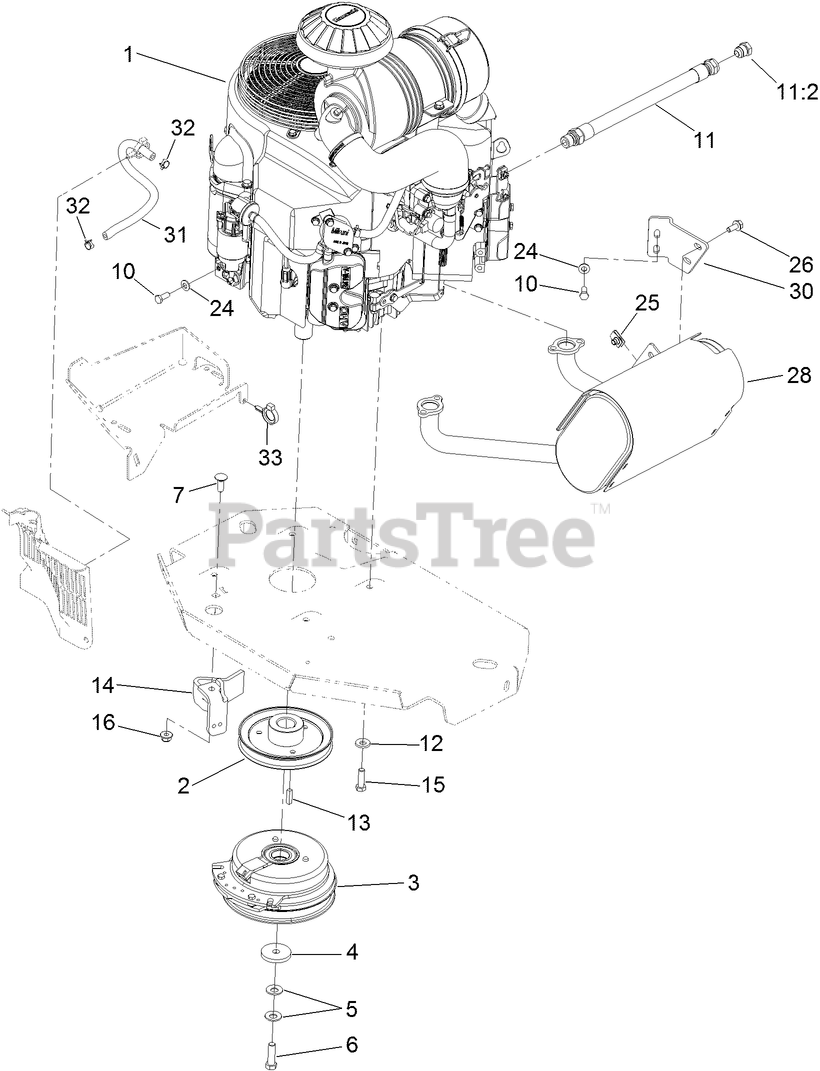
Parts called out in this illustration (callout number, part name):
2	SHEAVE
3	CLUTCH KIT
4	WASHER-CLUTCH
5	WASHER-SPRING
6	SCREW-HH, W/LOCTITE
7	SCREW-CARR
10	SCREW-HH
11	OIL DRAIN HOSE ASM
12	WASHER-BELLEVILLE
14	CLUTCH-ANCHOR
15	SCREW-HH
16	NUT-HF, NI
24	WASHER-SPRING
25	NUT-U
26	SCREW-HHF
28	MUFFLER
30	BRACKET-MUFFLER
31	HOSE-FUEL
32	CLAMP-HOSE
33	CLAMP-HOSE
